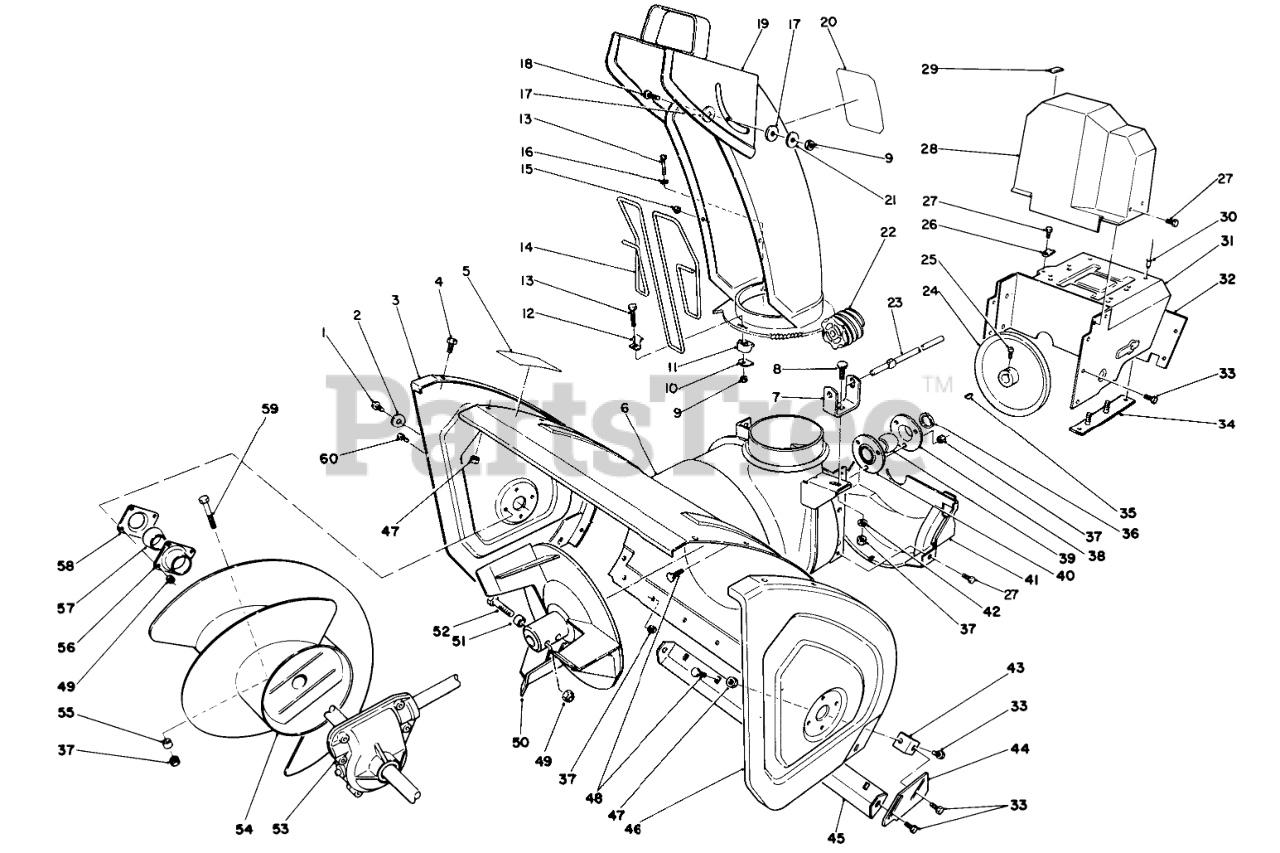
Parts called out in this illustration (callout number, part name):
1	SCREW-HH
2	WASHER
3	PLATE-SIDE, RH
4	SCREW-HHF
5	DECAL-WARNING, AUGER
6	Housing-28"
7	BRACKET-WORM, CHUTE
8	BOLT-CARR
9	NUT-LOCK, NI
10	PLATE-RETAINER, CHUTE
11	RETAINER-CHUTE
12	CLIP-GUARD, CHUTE
13	SCREW-HSH
14	GUARD-CHUTE
15	NUT-PUSH
16	WASHER-FLAT
17	WASHER-PLASTIC
19	Assembly
20	DECAL-DANGER DISCH.
21	WASHER-FLAT
22	GEAR-WORM
23	ROD-CHUTE, LOWER
24	PULLEY-IMPELLER
25	SCREW-SET, SQH
26	RETAINER-CABLE
27	SCREW-HWH
28	COVER-BELT, UPPER
29	COVER-CABLE
30	RIVET-POP
31	Frame-Engine
32	Cover-Frame, Engine
33	SCREW-HHF
34	PLATE ASM FRM LH 11 B&S
35	KEY-WOODRUFF
36	WASHER-THRUST
37	NUT-LOCK, NI
38	Flange-Bearing (Rear)
39	BEARING-BALL
40	Flange-Bearing (Front)
41	Cover-Belt (Lower)
42	WASHER-PLAIN
43	Bracket-Skid
44	Plate-Skid LH
45	Blade-Scraper
46	Plate-Side LH
47	NUT-LOCK, NI
48	SCREW-CARR
49	NUT-LOCK, NI
50	Impeller
51	SPACER
52	SCREW-HHF
53	Auger Gearbox Assembly
54	Auger-R.H.
55	SPACER-HUB, AUGER
56	BEARING-FLANGE, FRONT
57	BEARING
58	BEARING-FLANGE, REAR
59	Auger Bolt
60	SCREW-HH
